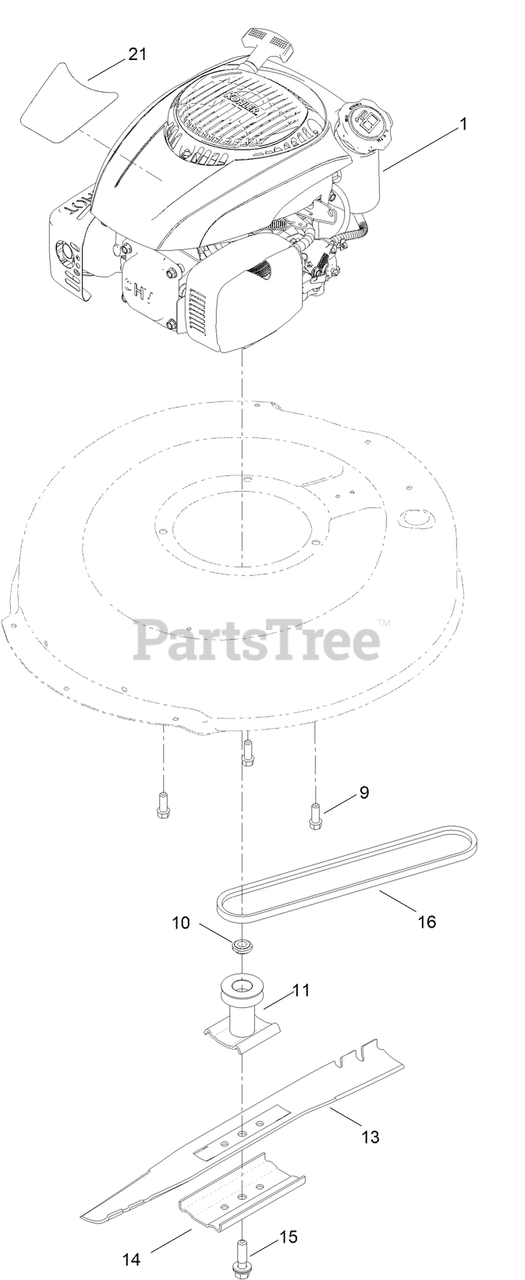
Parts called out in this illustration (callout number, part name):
9	SCREW-TAPTITE
10	SPACER-DRIVER
11	DRIVER-BLADE
14	SUPPORT-BLADE
15	BOLT-BLADE
